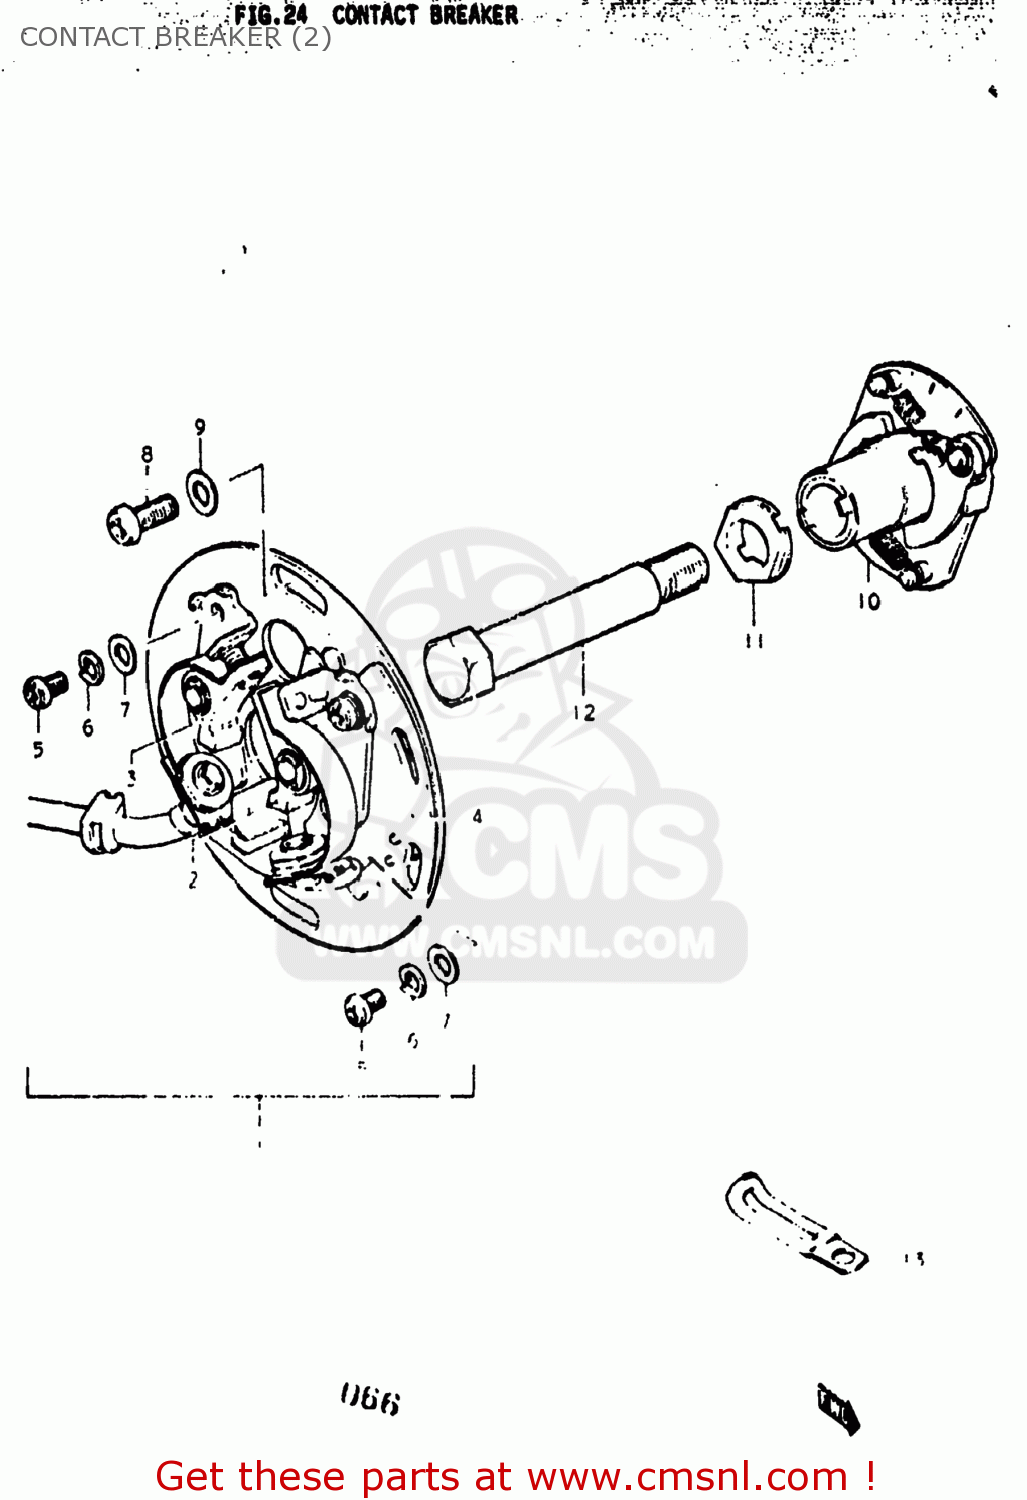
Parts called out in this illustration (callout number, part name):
1	SIGNAL GENERATOR ASSEMBLY
2	POINT ASSEMBLY,CONTACT
3	POINT ASSEMBLY,CONTACT
4	PLATE,CONTACT POINT
5	SCREW
6	LOCK WASHER
7	WASHER
8	SCREW(5X12)
9	WASHER 5MM
10	GOVERNOR ASSEMBLY
11	WASHER
12	BOLT
13	CLAMP L:35
